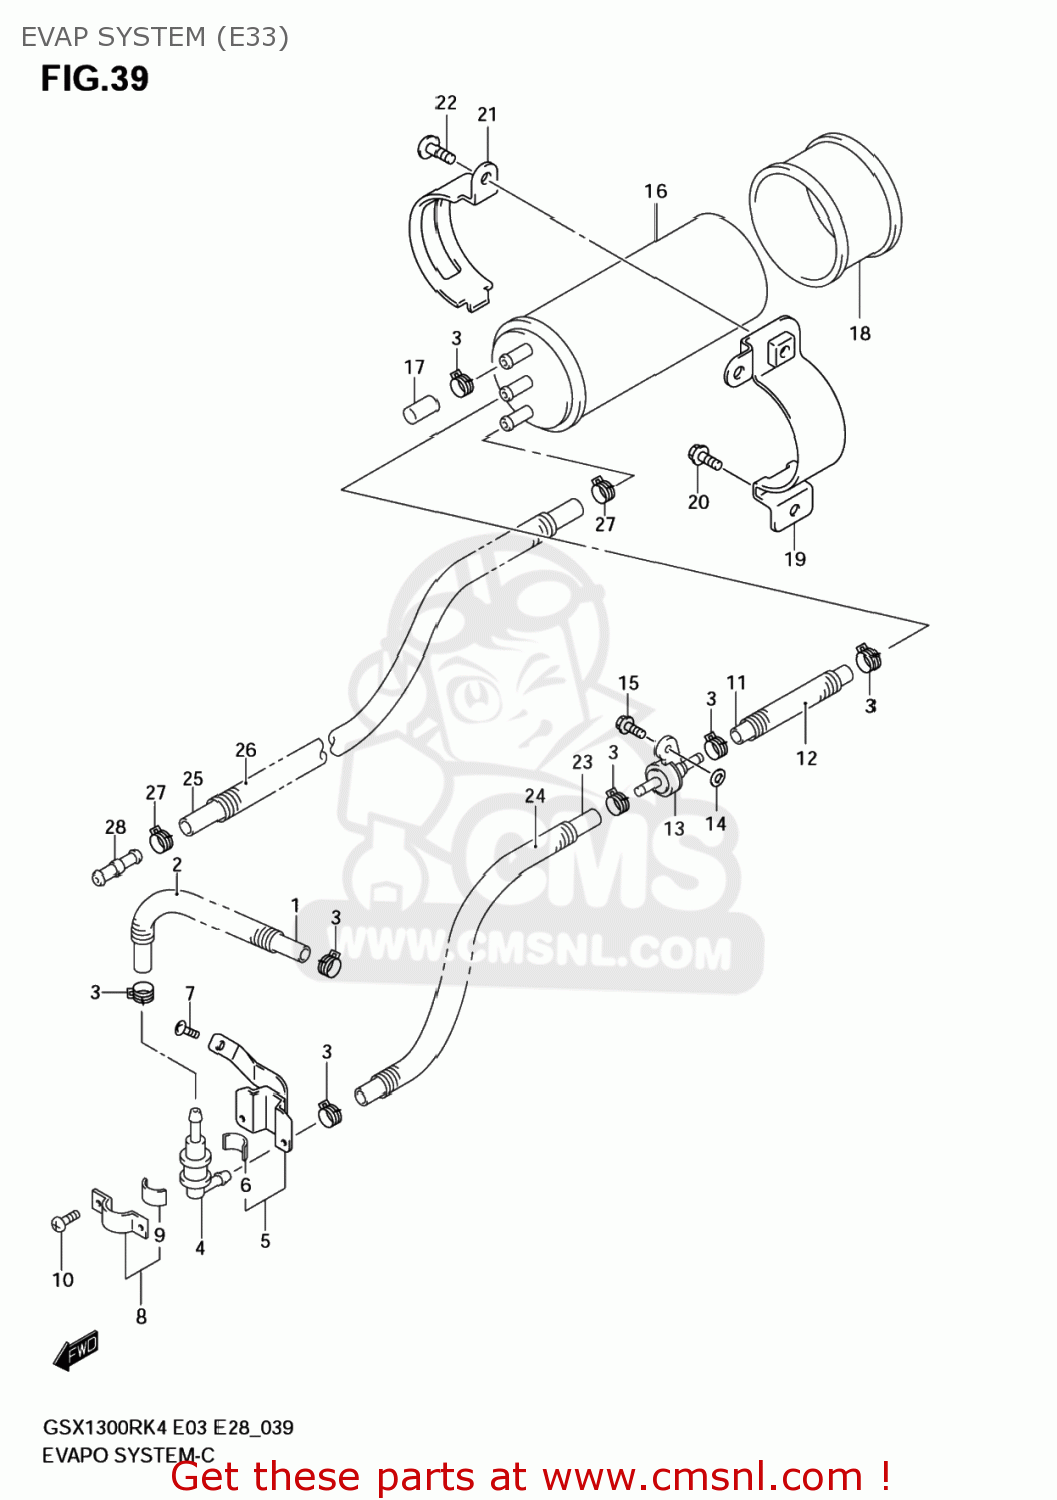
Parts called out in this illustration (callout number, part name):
1	HOSE,TANK & BREATHER VALVE
2	SPRING
3	CLIP
4	VALVE,FUEL TANK BREATHER
5	PLATE,TANK BREATHER VALVE
6	CUSHION
7	SCREW
8	PLATE,FUEL TANK BREATHER NO.2
9	CUSHION
10	SCREW
11	HOSE(5.4X11.4X600)
12	SPRING
13	VALVE,2 WAY & BREATHER VALVE
14	WASHER(6.5X20X1.2)
15	BOLT
16	CANISTER ASSY,CHARCOAL
17	CAP,OD:11.5
18	CUSHION,CANISTER
19	BRACKET,CANISTER
20	BOLT
21	HOLDER,CANISTER
22	SCREW
23	HOSE(5.4X11.4X600)
24	SPRING
25	HOSE(5.4X11.4X600)
26	SPRING
27	CLIP
28	UNION
